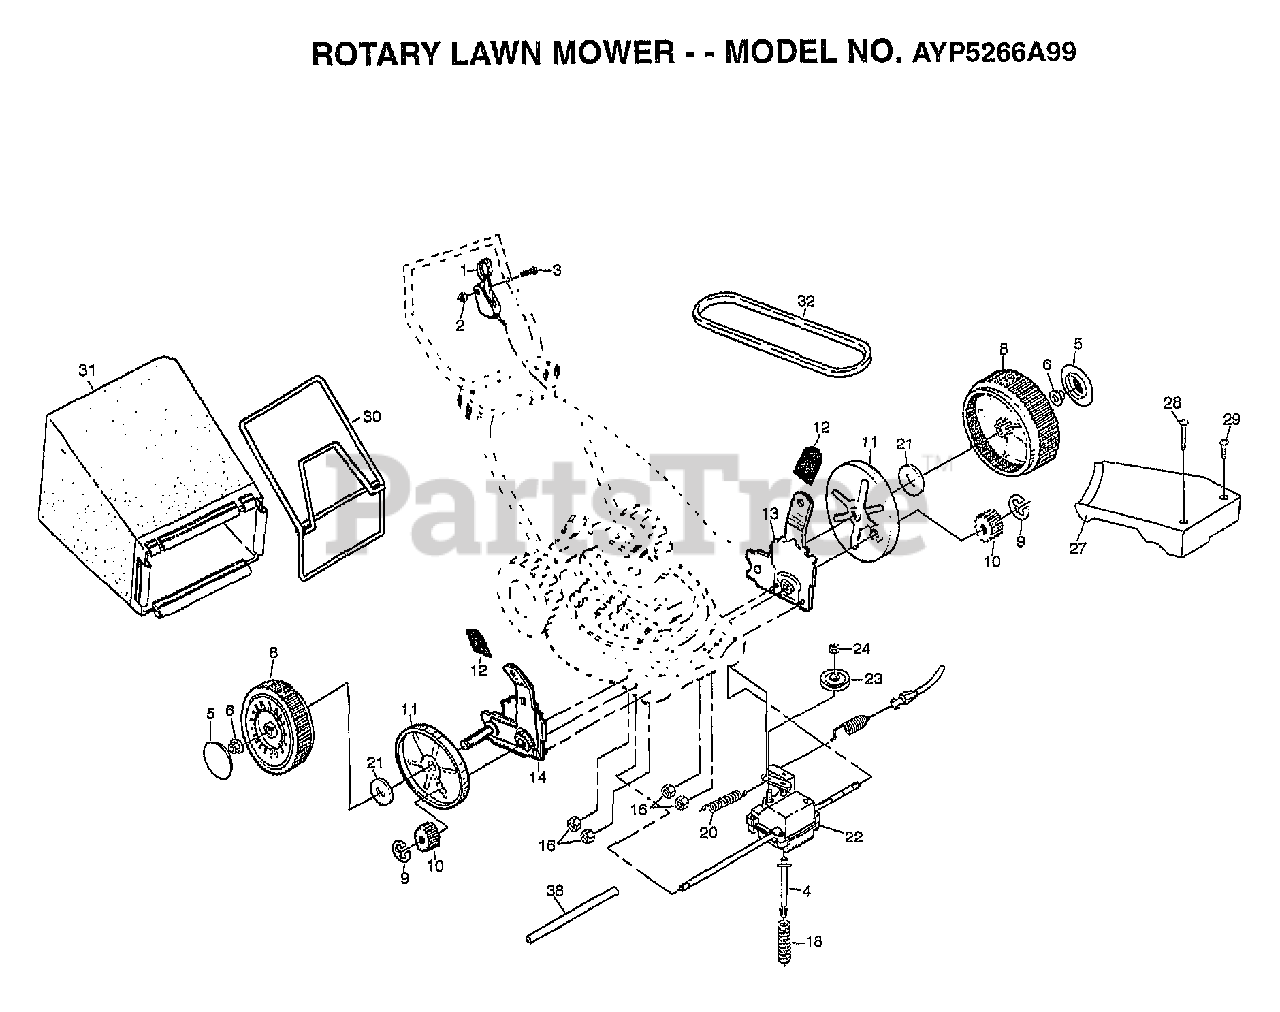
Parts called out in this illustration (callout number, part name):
1	CONTROL.DRV.56.25
2	LOCKNUT
3	PAN HEAD SCREW
4	SPRING.RETAINER.
5	HUB CAP
6	NUT.HXFLG.LOCK.
8	WHEEL.8X2.LP.PR
9	E-RING.7/16.RE.
10	PINION.GEAR
11	DUST SHROUD PM
12	KNOB PM
13	WHEEL.ADJ.ASM.LH.
14	WHEEL.ADJ.ASM.RH.
18	SPRING.TENSION
20	SPRING
21	WASHER FLUT
23	PULLEY.DRIVEN
24	LOCKNUT
27	"COVER.DRIVE 22""RD"
28	SCREWL.SLOT.TORXT
29	SCREW.SLOT.TORTX.
30	FRAME.CATCHER.2.5
31	GRASSBAG.250B1.BL
38	DRV SHAFT TUBE PM
